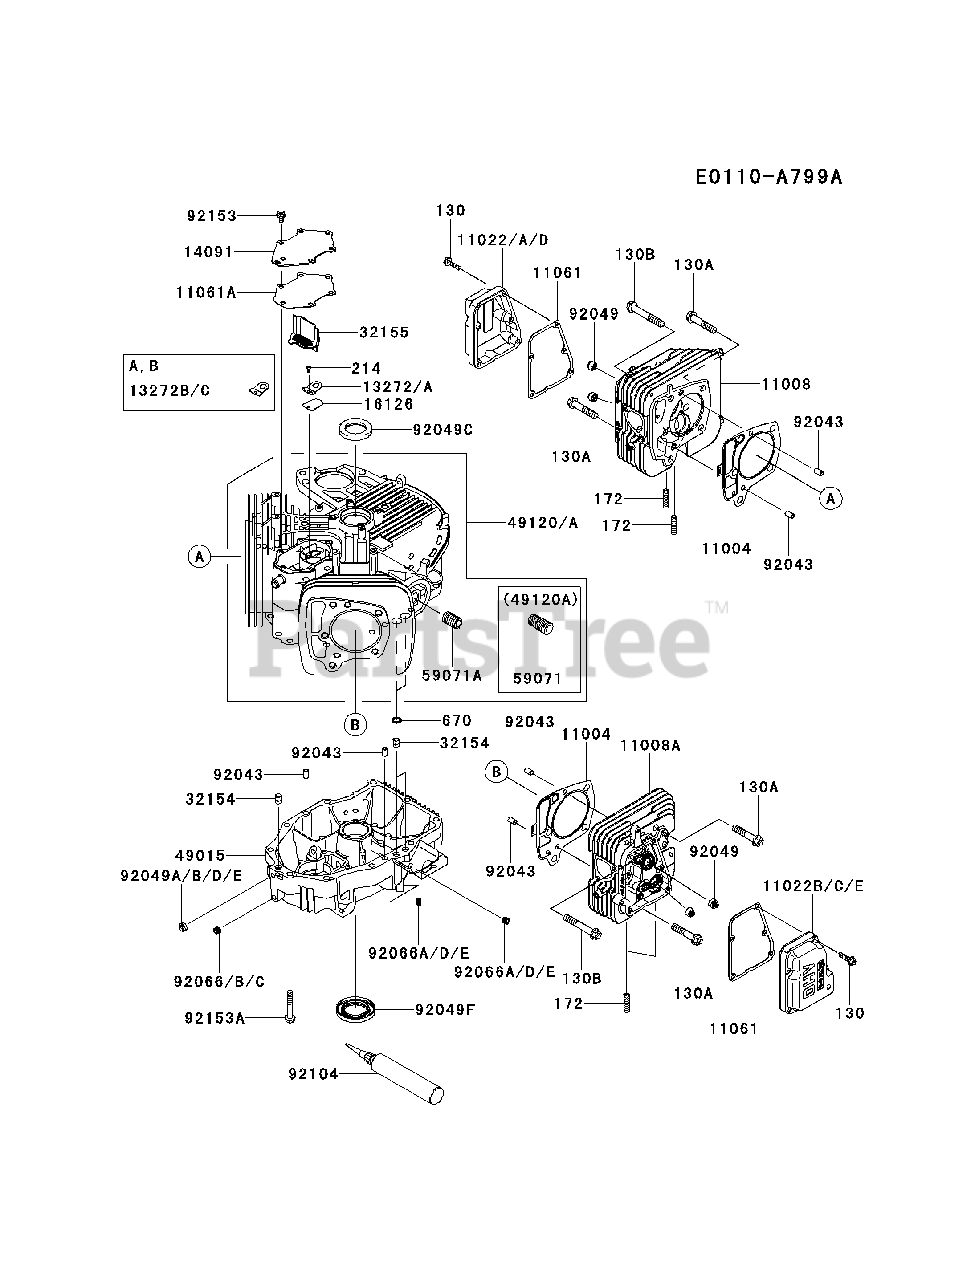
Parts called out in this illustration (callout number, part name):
130	BOLT-FLANGED,6X25
130A	BOLT-FLANGED,10X50
130B	BOLT-FLANGED,10X65
172	BOLT-STUD,8X18
214	SCREW-PAN+-,4X8
670	O RING,11MM
92153A	BOLT,8X50
